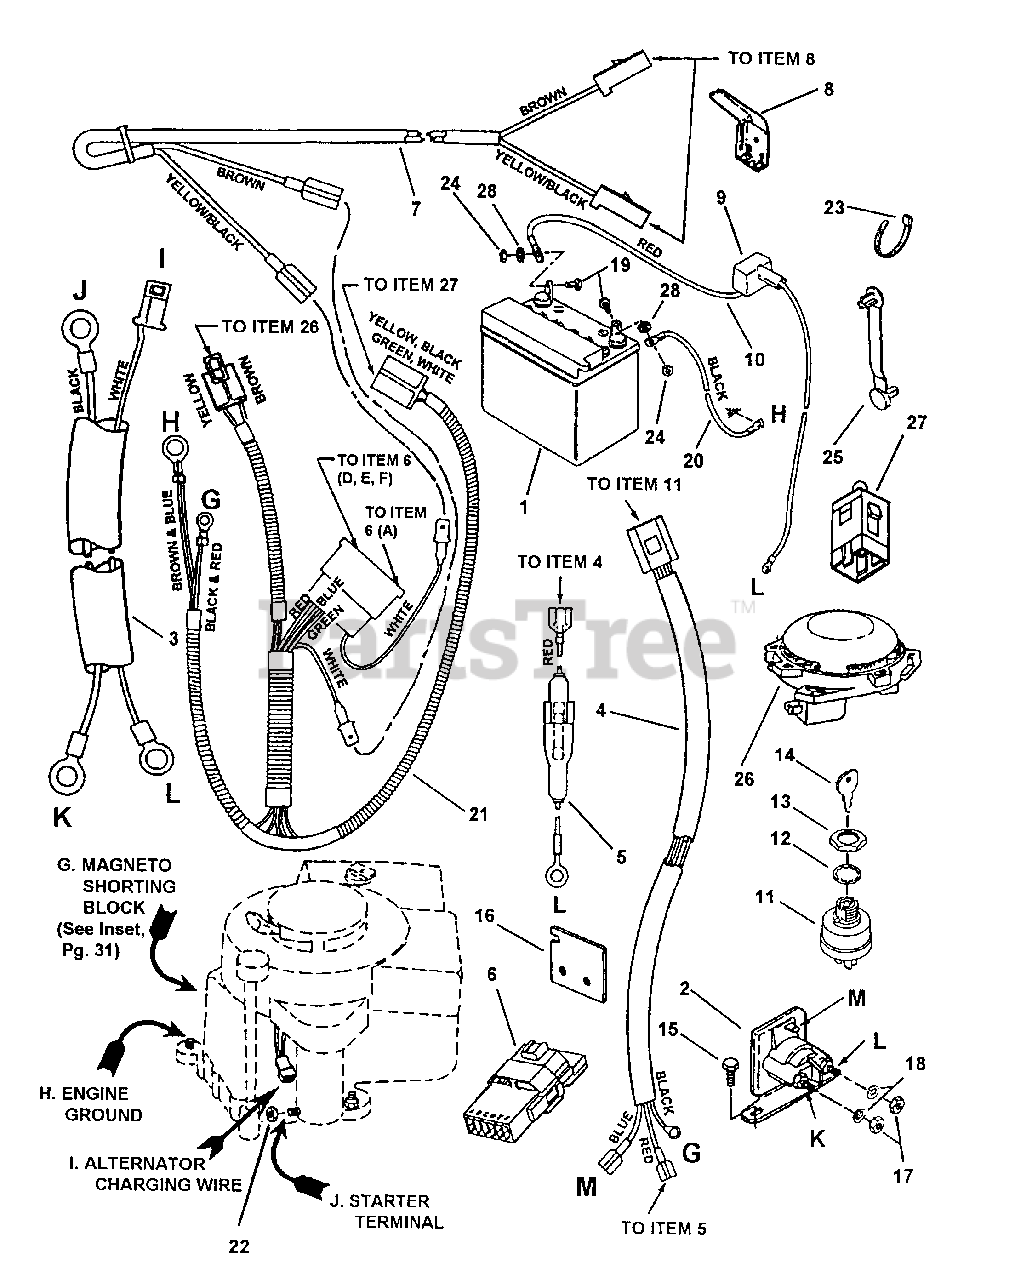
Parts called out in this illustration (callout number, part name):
1	KIT, 12V Dry Charge Battery
2	SOLENOID
3	HARNESS, Starter Wiring
4	HARNESS, Ignition Wiring
5	HOLDER, Fuse
6	INTERLOCK Module
7	HARNESS, (Deck Interlock Wiring)
8	SWITCH, Deck Interlock (NO)
9	COVER, Battery Cable
10	CABLE, Positive (Red)
11	SWITCH, Ignition (Includes keys #11138)
12	WASHER, 5/8" Internal Tooth Lock
13	NUT, 5/8-32 Hex
14	KEY, Switch
15	SCREW, 1/4-20 x 1/2" Hex Washer Self-Tap
16	PROTECTOR, Solonoid
17	NUT, 1/4-20 Hex, Grade 5 or B
18	WASHER, 1/4" Internal Tooth Lock
19	SCREW, 1/4-20 x 5/8" Hex Head Cap, Grade,5
20	CABLE, Negative
21	HARNESS, Operator Presence Control Wire
22	NUT, 1/4-20 Hex, Grade 5 or B
23	TIE, 7" long Cable
24	NUT, 1/4-20 Hex Center Lock, Grade 5 or B
25	TIE, 2" Long Cable
26	SWITCH, Seat (NC)
27	SWITCH, Operator Presence Control (OPC) Traction (NC/NO)
28	RETAINER, 1/4" Bolt
